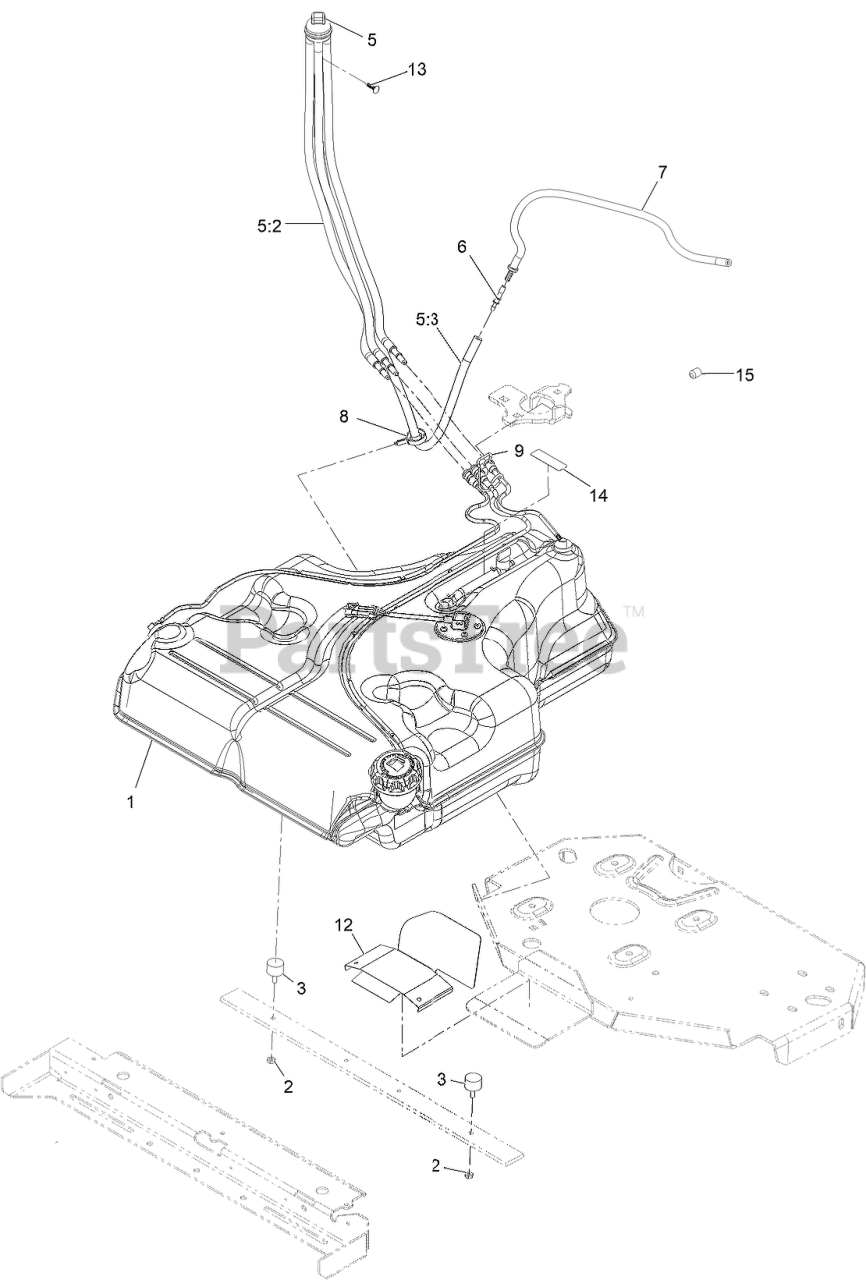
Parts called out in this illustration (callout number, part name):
1	FUEL TANK ASM
2	NUT-JAM
5	FUEL MANIFOLD VENT ASM
5:2	HOSE-FUEL
5:3	HOSE-FUEL
6	BARB-FUEL
7	HOSE-FUEL
8	CLAMP-HOSE
9	RETAINER-LINE, VAPOR
12	GUARD-EXHAUST
13	PLUG-PLASTIC
14	DECAL-STRIP BLACK
15	PLUG-PORT
